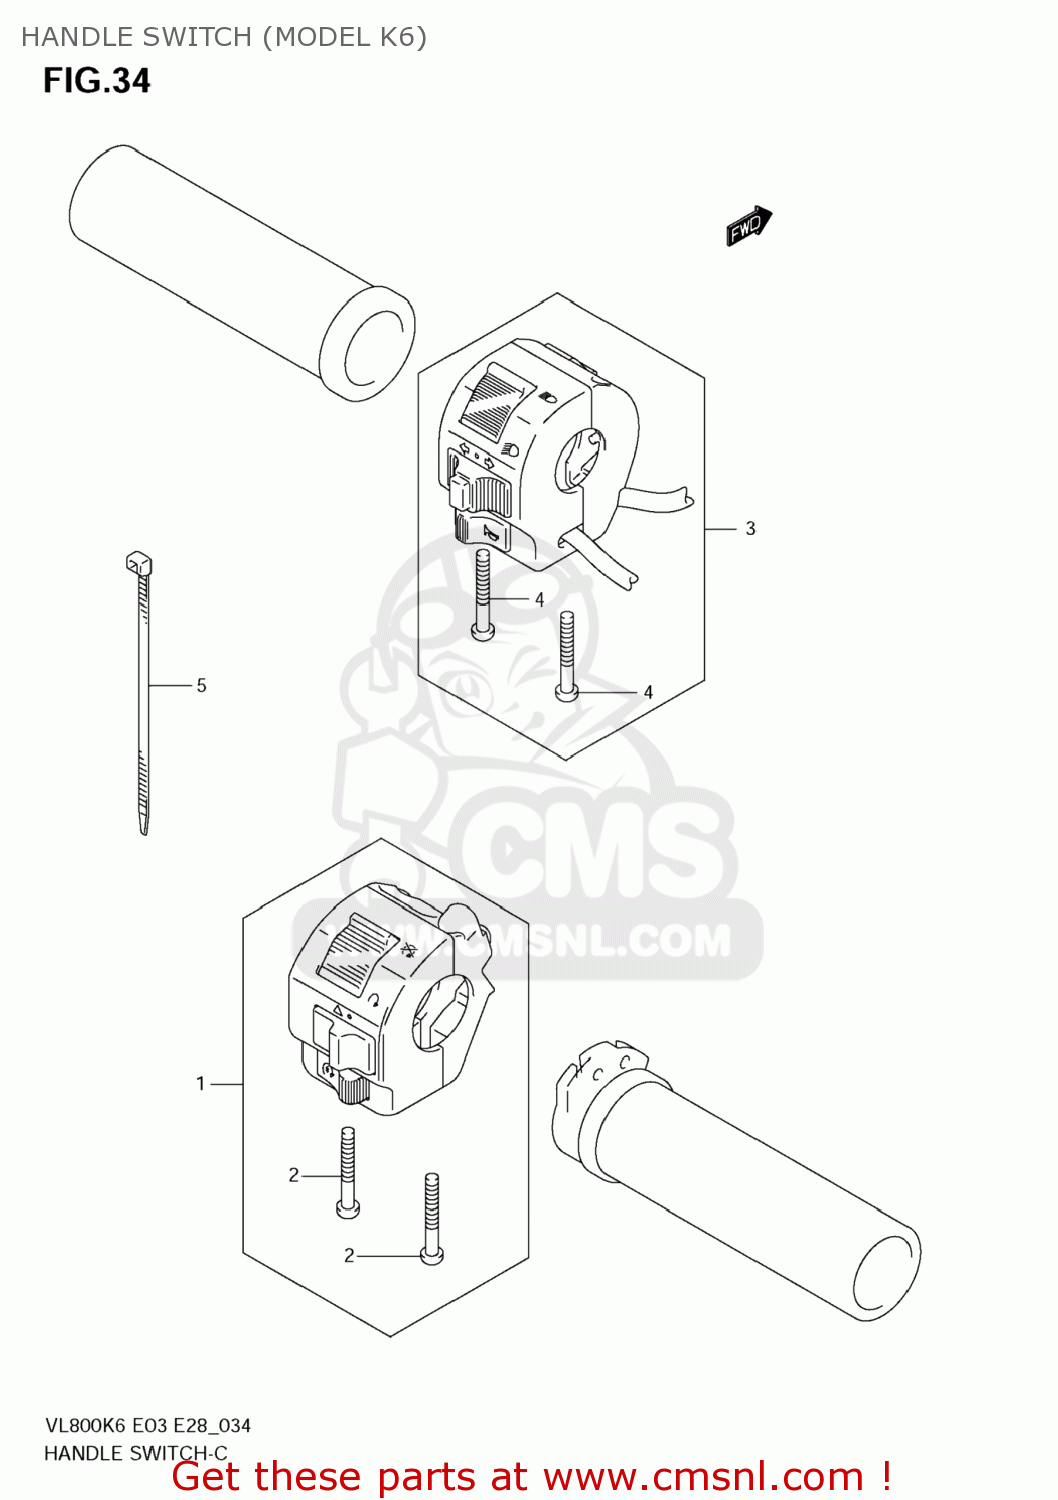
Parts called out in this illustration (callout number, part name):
1	SWITCH ASSY,HA
2	SCREW(5X16)
3	SWITCH ASSY,HANDLE,L
4	SCREW(5X16)
5	CLAMP(L:145)
